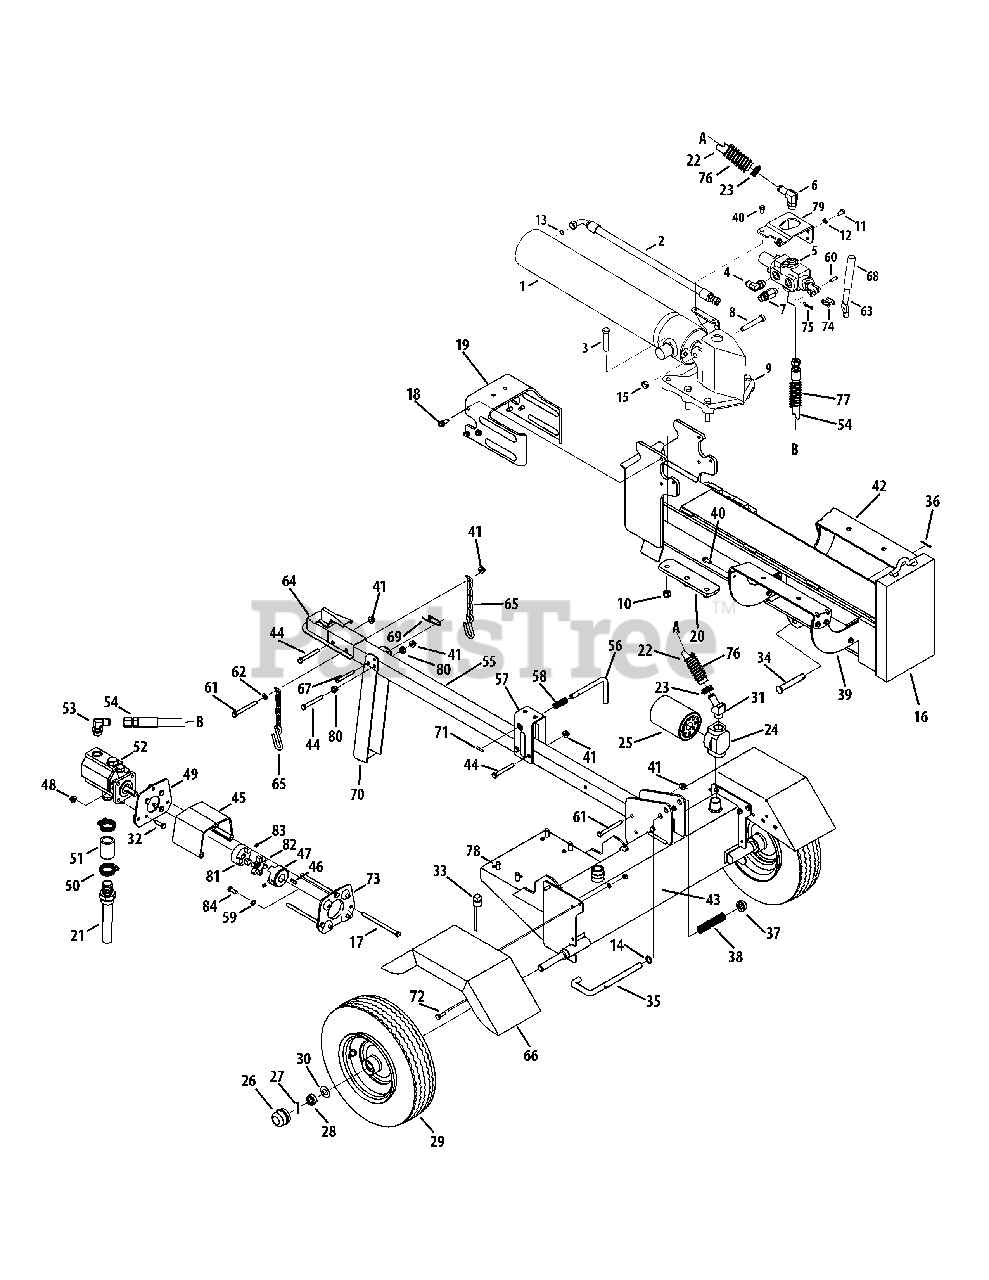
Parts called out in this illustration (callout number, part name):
1	Hydraulic Cylinder
2	Hydraulic Tube
3	Hex Cap Screw, 1/2-20 x 2.75
4	90 Degree Solid Adapter
5	Control Valve
6	Return Elbow
7	Nipple Pipe, 1/2-14
8	Hex Cap Screw, 1/2-13 x 3.25
9	Wedge Assembly
10	Hex Lock Nut, 1/2-20
11	Hex Cap Screw, 3/8-16 x .75
12	Lock Washer, 3/8
13	O-Ring, .489 ID x .070 Dia.
14	Flat Washer, .635 x.93 x.06
15	Hex Lock Nut, 1/2-13
16	Beam Assembly
17	Hex Screw, 5/16-18 x 4.75
18	Self Tapping Screw, 3/8-16 x 1.0
19	Dislodger Bracket
21	Inlet Filter
22	Return Hose, 3/4 x 44
23	Hose Clamp, 5/8
24	Filter Housing
25	Oil Filter
27	Cotter Pin
28	Slotted Nut, 3/4-16
29	Complete Wheel Assembly
29	Dust Seal
29	Roller Bearing
30	Flat Washer, .760 x.500
31	Hydraulic Fitting, 1 1/16 Orb x .75
32	Hex Screw, 5/16-18 x 1.00
33	Vented Dipstick
34	Clevis Pin
36	Cotter Pin
38	Compression Spring
39	Log Tray Bracket
40	Hex Washer Screw, 5/16-18 x .750
41	Flange Lock Nut, 3/8-16
43	Frame Assembly
44	Hex Bolt, 3/8-16 x 3
45	Coupling Shield
46	Square Key, 3/16" x .75
47	Coupling, .875
48	Flange Lock Nut, 5/16-18
49	Rear Coupling Support Bracket
50	Hose Clamp, 5/8
53	45 Degree Elbow Fitting
54	High Pressure Hydraulic Hose
55	Tongue Assembly
56	Latch Rod
58	Compression Spring
59	Lock Washer, 5/16
60	Clevis Pin
61	Hex Cap Screw, 3/8-16 x 3.50
62	Flat Washer, .375 x.738 x.063
63	Hydraulic Valve Control
64	Hitch Coupling Assembly
67	Clevis Pin
69	Spring Pin
71	Spiral Pin
72	Self-Tapping Screw, 5/16-18 x 1.00
73	Front Coupling Support Bracket
74	Valve Handle Link
75	Cotter Pin, Bow Tie
76	Hose Guard, 44"
77	Hose Guard, 48"
78	Sems Screw, 3/8-16 x 1.00
79	Outer Valve Bracket
80	Plastic Bushing, .380 ID
81	Coupling, .500
82	Spider Bushing
83	Set Screws
84	Hex Cap Screw, 5/16-24 x .75
